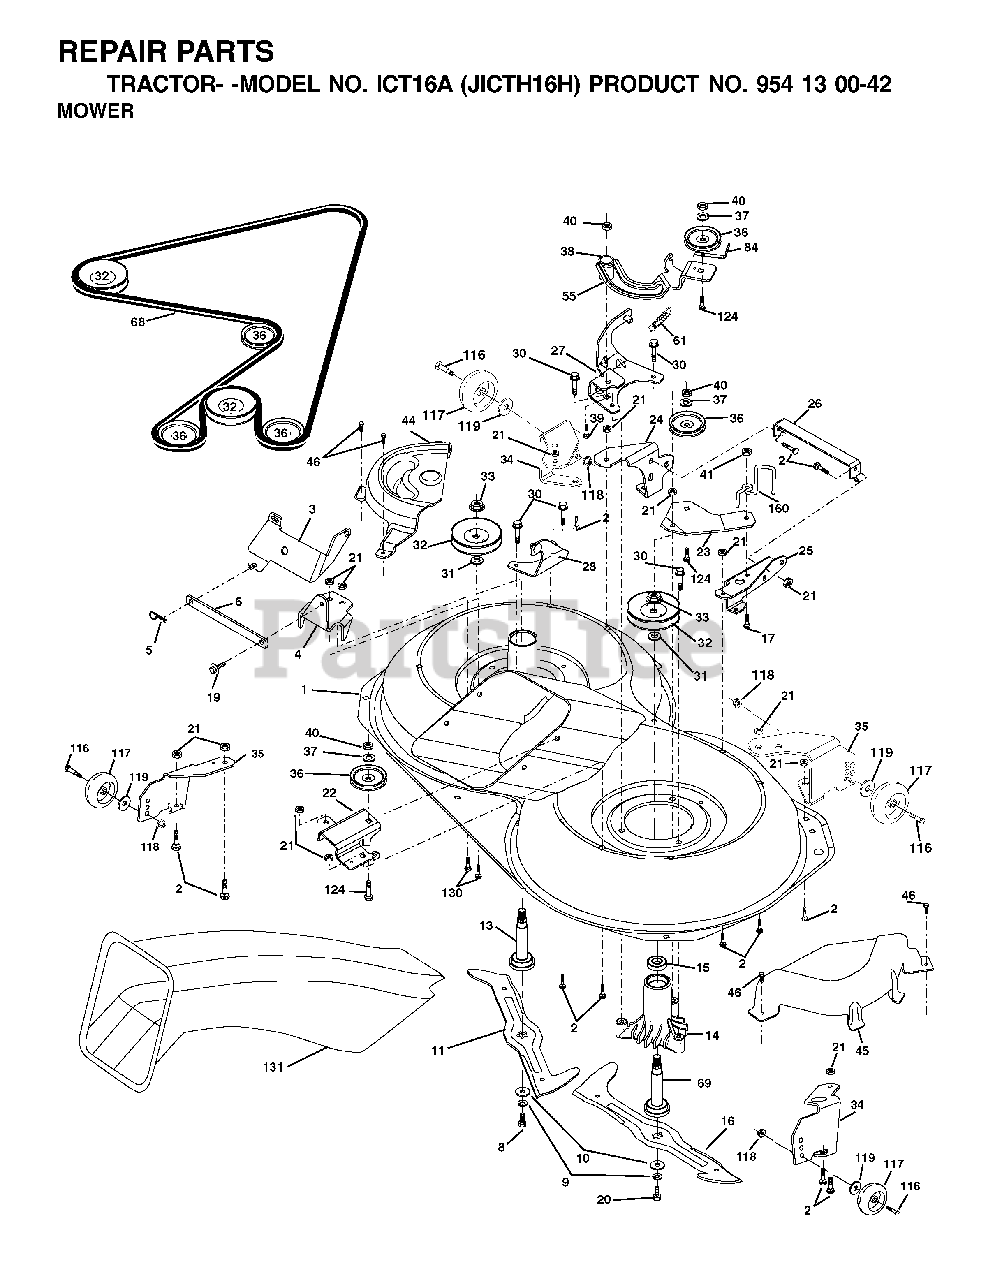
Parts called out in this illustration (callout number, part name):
2	BOLT
3	BRACKET
5	RETAINER-SPRNG RB
6	BAR SWAY
8	BLADE BOLT
9	LOCKWASHER
10	WASHER.BLADE
11	BLADE, LH (CTH150)
13	SHAFT ASM VENT
14	HSG MANDREL
16	RP BLADE RH (CTH150)
17	BOLT.3/8-14X1.25
19	BOLT SHD 5/16-18
21	LOCKNUT
22	BRACKET
23	BRACKET
26	BRACE
27	BRACKET
30	SCREW, WASHER HEAD
31	WASHER
33	NUT, FLG TOPLOCK 9/16"
36	PULLEY.IDLER.4.25
40	LOCKNUT
41	NUT LOCK FLG 3/8-16 UNC
45	MANDREL COVER RH
46	SCREW.1/4-20X5/8
55	ARM IDLER
68	HEX-BELT 107 MOWER
69	SHAFT.ASM.W/LWR.BRG.RH.THREAD
84	KEEPER, BELT IDLER
116	BOLT, SHOULDER
117	WHEEL GAGE DONUT
118	LOCKNUT
119	WASHER
124	BOLT.3/8-16X1.50
131	CHUTE BAGGER
